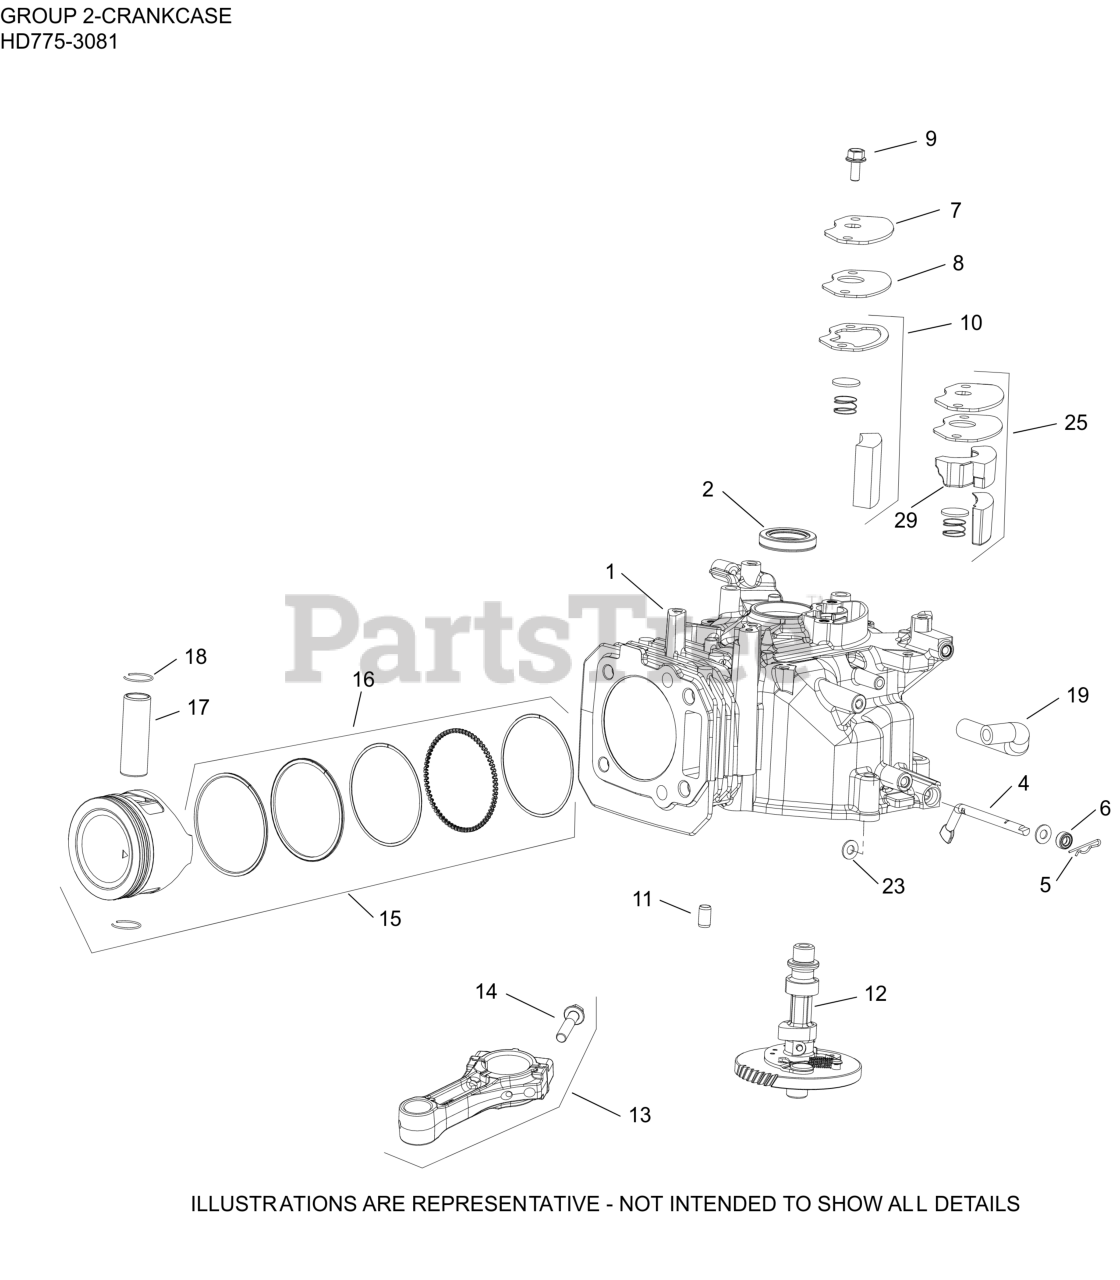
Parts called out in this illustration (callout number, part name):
1	CRANKCASE
2	SEAL, CCASE/FLYWHEEL
4	SHAFT, GOVERNOR CROSS
5	CLIP, GOVERNOR SHAFT
6	SEAL, OIL
7	COVER, BREATHER
8	GASKET, BREATHER COVER
9	SCREW, HEX FLANGE (M6)-USE 25 086 433-S
10	KIT, BREATHER FILTER
11	PIN, DOWEL (8mm)
12	CAMSHAFT ASSEMBLY
13	CONNECTING ROD
14	SCREW, HEX FLANGE (M7)
15	KIT, PISTON
17	PIN, PISTON
18	RETAINER, PISTON PIN
19	HOSE, BREATHER
23	WASHER, FLAT (DIA 13mm O.D.)
25	KIT, BREATHER FILTER
29	FILTER, BREATHER MEDIA-USE 14 050 31-S
